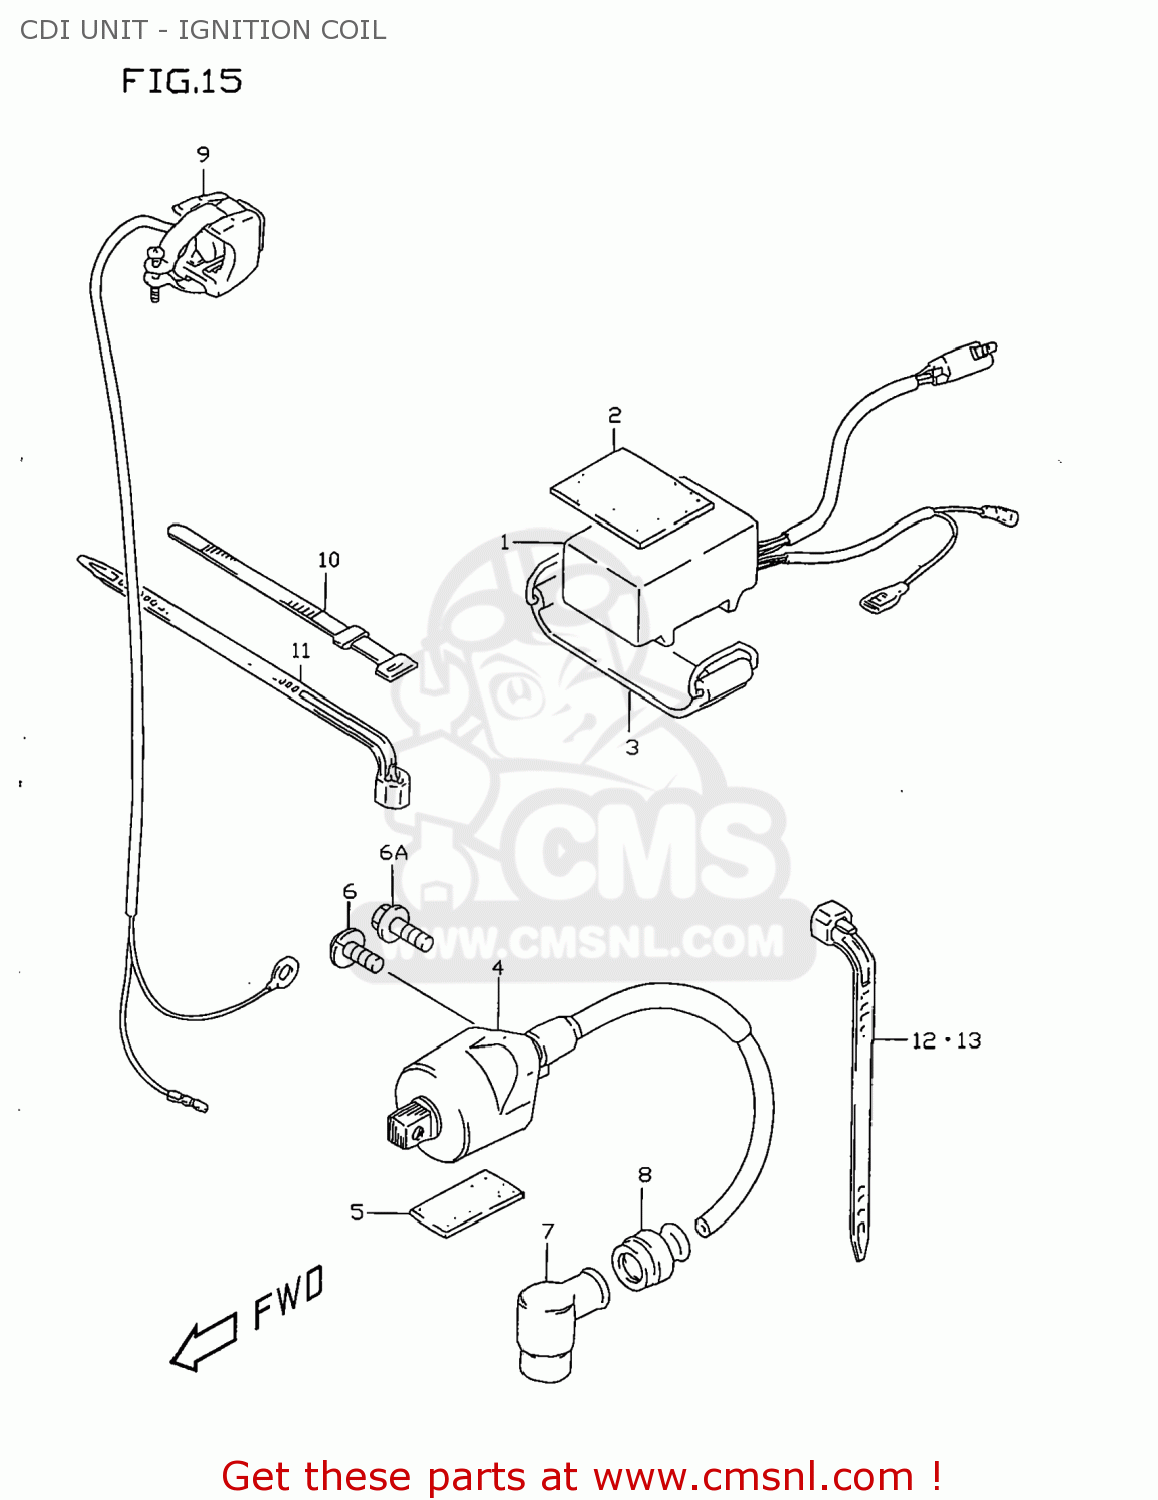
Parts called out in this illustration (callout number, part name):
1	CDI UNIT
2	PROTECTOR(170X95X3.0)
3	BAND
4	COIL ASSY,IGNITION
5	PROTECTOR(170X95X3.0)
6	SCREW(6X21)
6A	SCREW
7	CAP,SPARK PLUG
8	SEAL,HIGH TENSION CORD
9	SWITCH ASSY,ENGINE STOP
10	CLAMP(L:120)
11	CLAMP L:165
12	CLAMP(L:125)
13	CLAMP(L:95)
